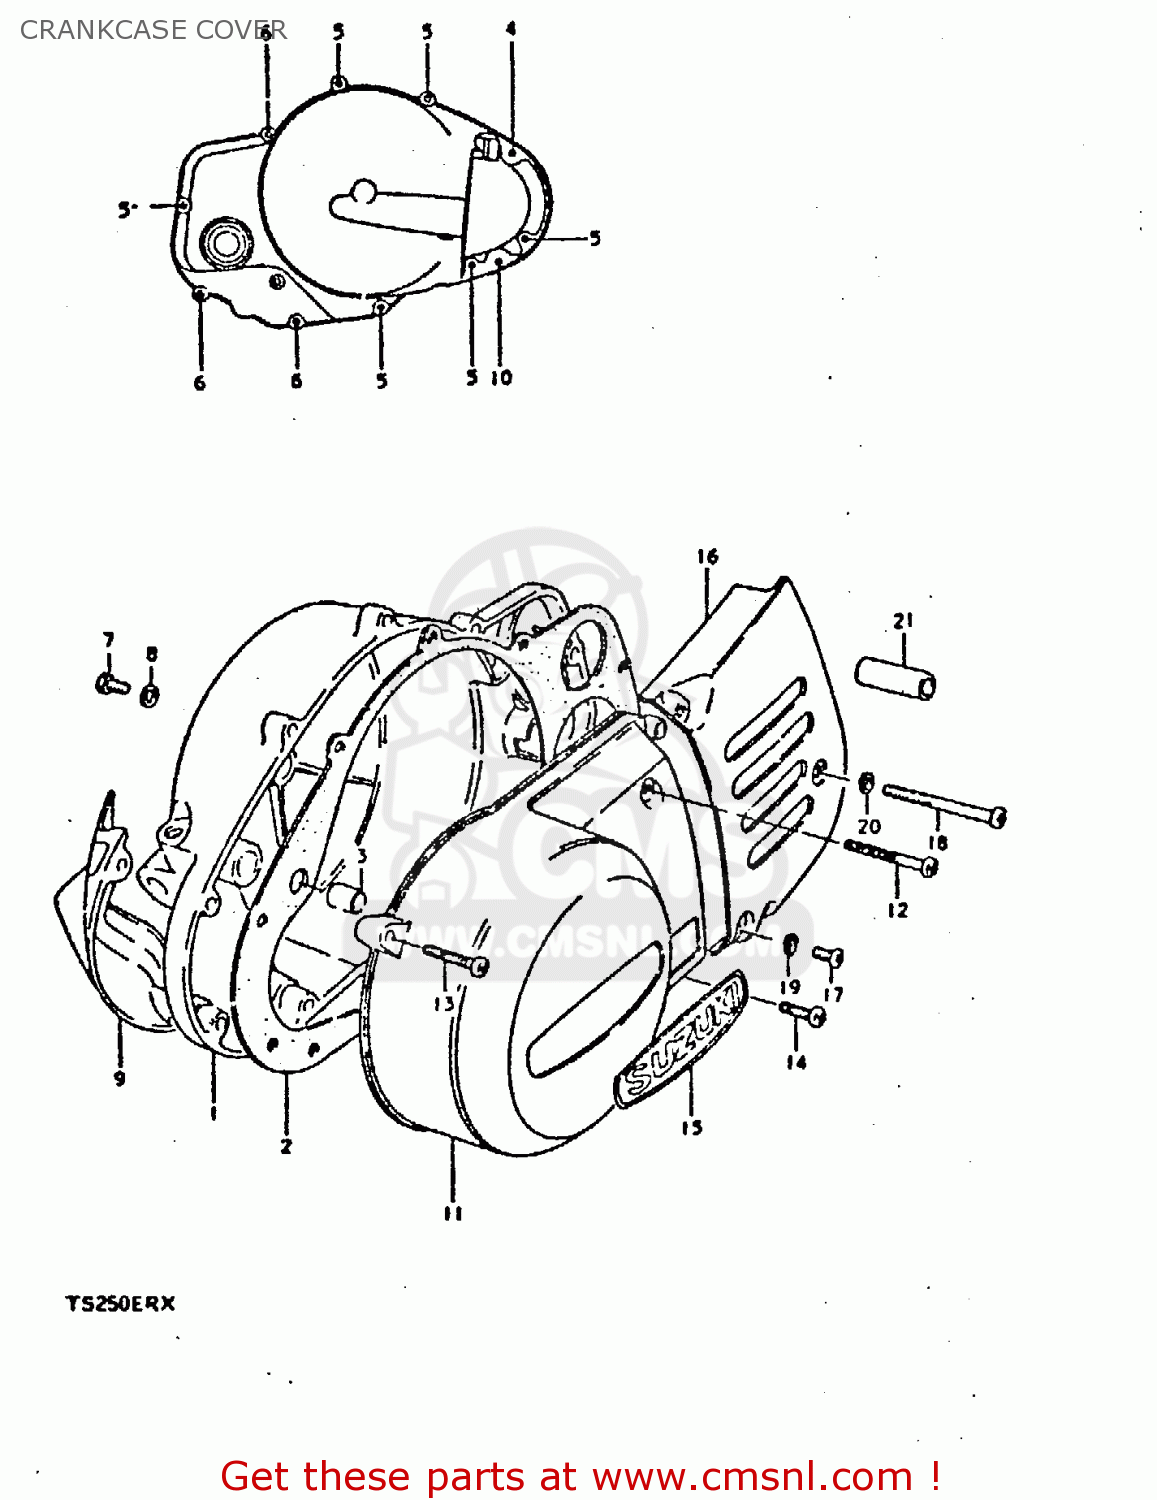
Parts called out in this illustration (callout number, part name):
1	COVER,CLUTCH
2	GASKET,CLUTCH COVER (MCA)
3	PIN
4	SCREW 6X30
5	SCREW
6	SCREW
7	SCREW(6X10)
8	GASKET(6.2X11X1) (NAS)
9	COVER,CLUTCH RELEASE A
10	SCREW
11	COVER,MAGNETO
12	SCREW (6X35)
13	SCREW
14	SCREW
15	EMBLEM,MAGNETO COVER
16	COVER,SPROCKET
17	SCREW
18	SCREW 6X60
19	LOCK WASHER
20	LOCK WASHER
21	CUSHION
